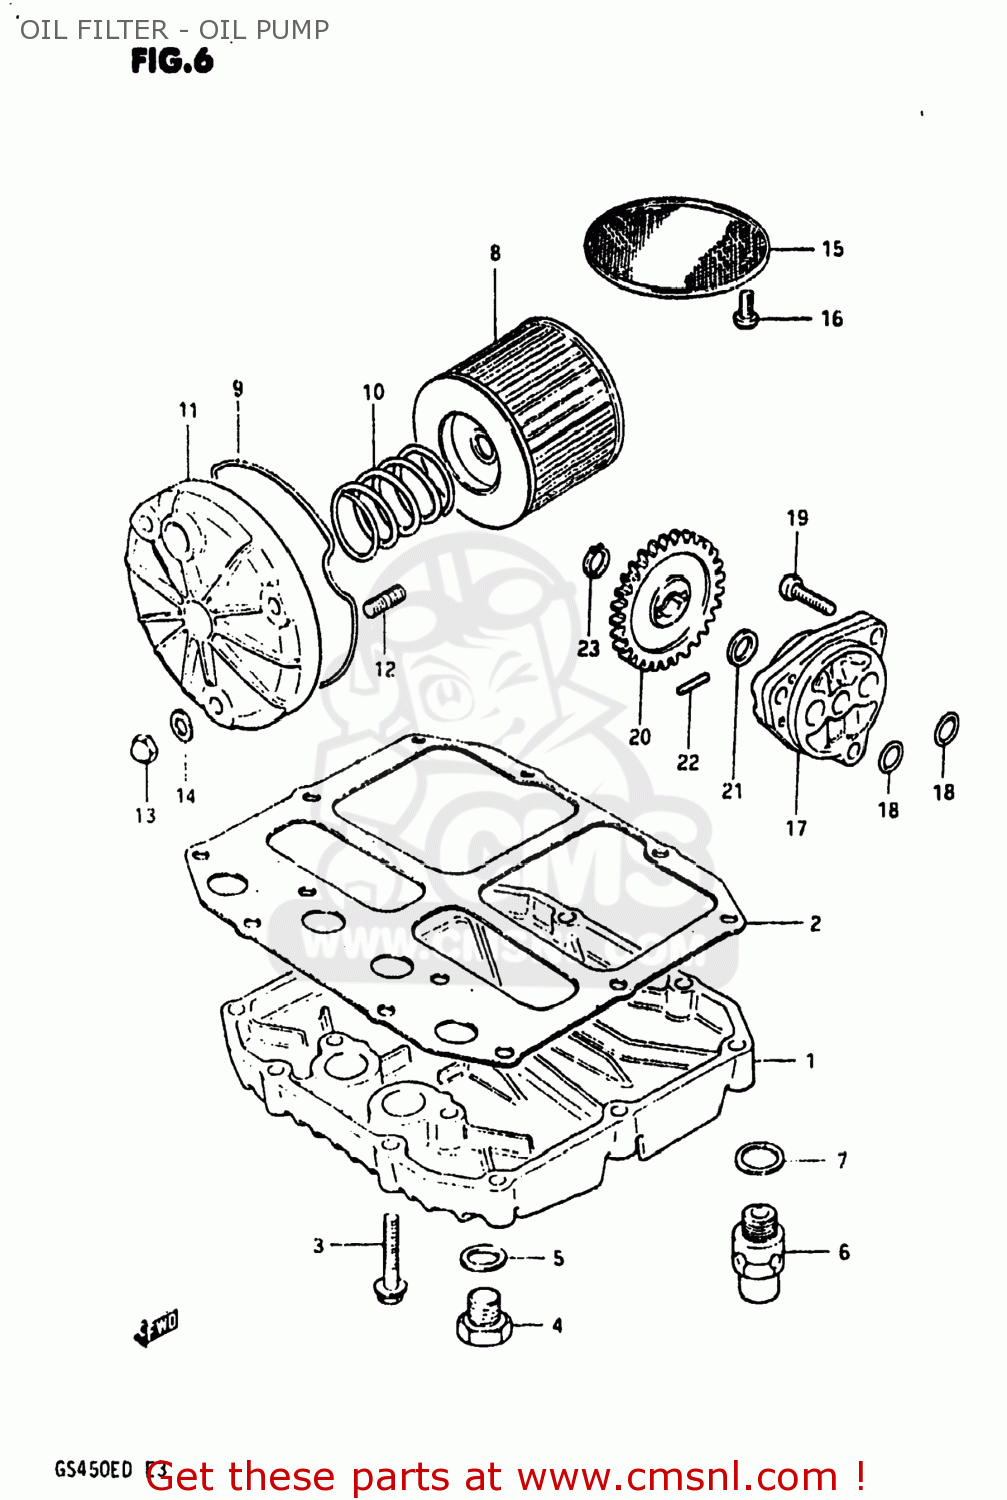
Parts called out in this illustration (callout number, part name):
1	PAN,OIL
2	GASKET,OIL PAN (MCA)
3	BOLT
4	PLUG
5	GASKET(14X19.2X2) (NAS)
6	REGULATOR ASSEMBLY,ENGINE
7	WASHER
8	FILTER ASSY,ENGINE OIL
9	O RING,OIL FILTER CHAMBER CAP
10	SPRING
11	CAP,OIL FILTER
12	STUD 6X20
13	NUT
14	WASHER
15	STRAINER,ENGINE OIL
16	SCREW 6X12
17	PUMP ASSY,ENGINE OIL
18	O RING(D:1.9,ID:13)
19	SCREW
20	GEAR,OIL PUMP DRIVEN
21	SHIM
22	PIN(4X15.8)
23	CIRCLIP
